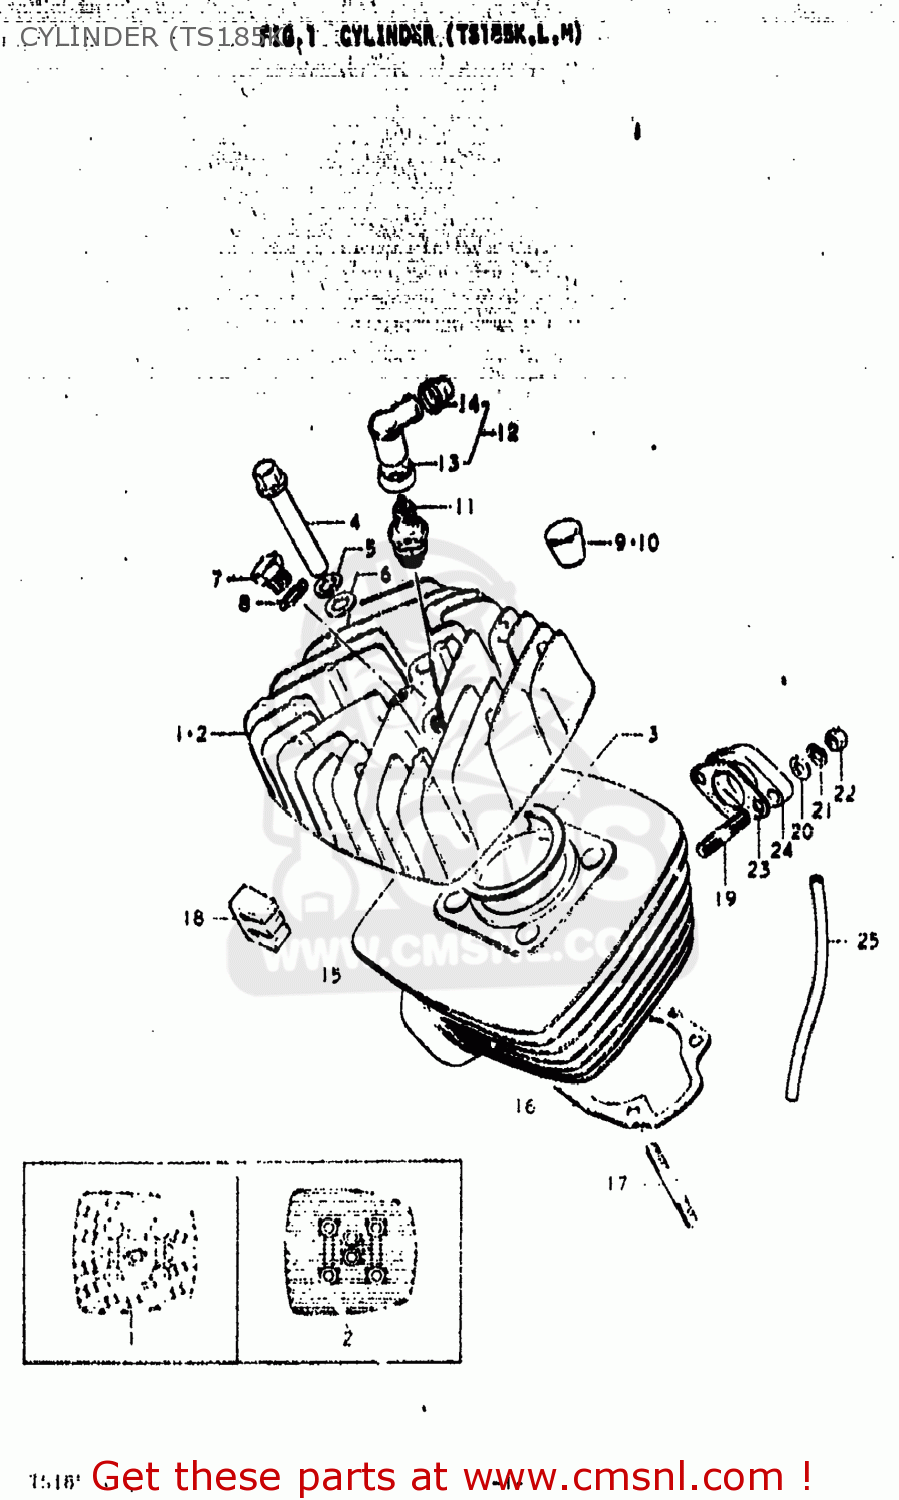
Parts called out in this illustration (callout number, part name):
1	HEAD,CYLINDER
2	HEAD,CYLINDER
3	GASKET,CYLINDER HEAD (NAS)
4	NUT
5	WASHER,LOCK 12
6	WASHER
7	PLUG
8	GASKET(14X19.2X2) (NAS)
9	PAD,CYLINDER HEAD
10	PAD,CYLINDER HEAD
11	SPARK PLUG
12	CAP,SPARK PLUG
13	SEAL,SPARK PLUG
14	SEAL,SPARK PLU
15	CYLINDER
16	GASKET,CYLINDER (MCA)
17	STUD BOLT
18	PAD,CYLINDER
19	STUD BOLT
20	WASHER
21	LOCK WASHER
22	LOCK WASHER
23	GASKET,CARBURETOR (MCA)
24	GASKET,CARBURETOR INSULATOR (NAS)
25	HOSE
